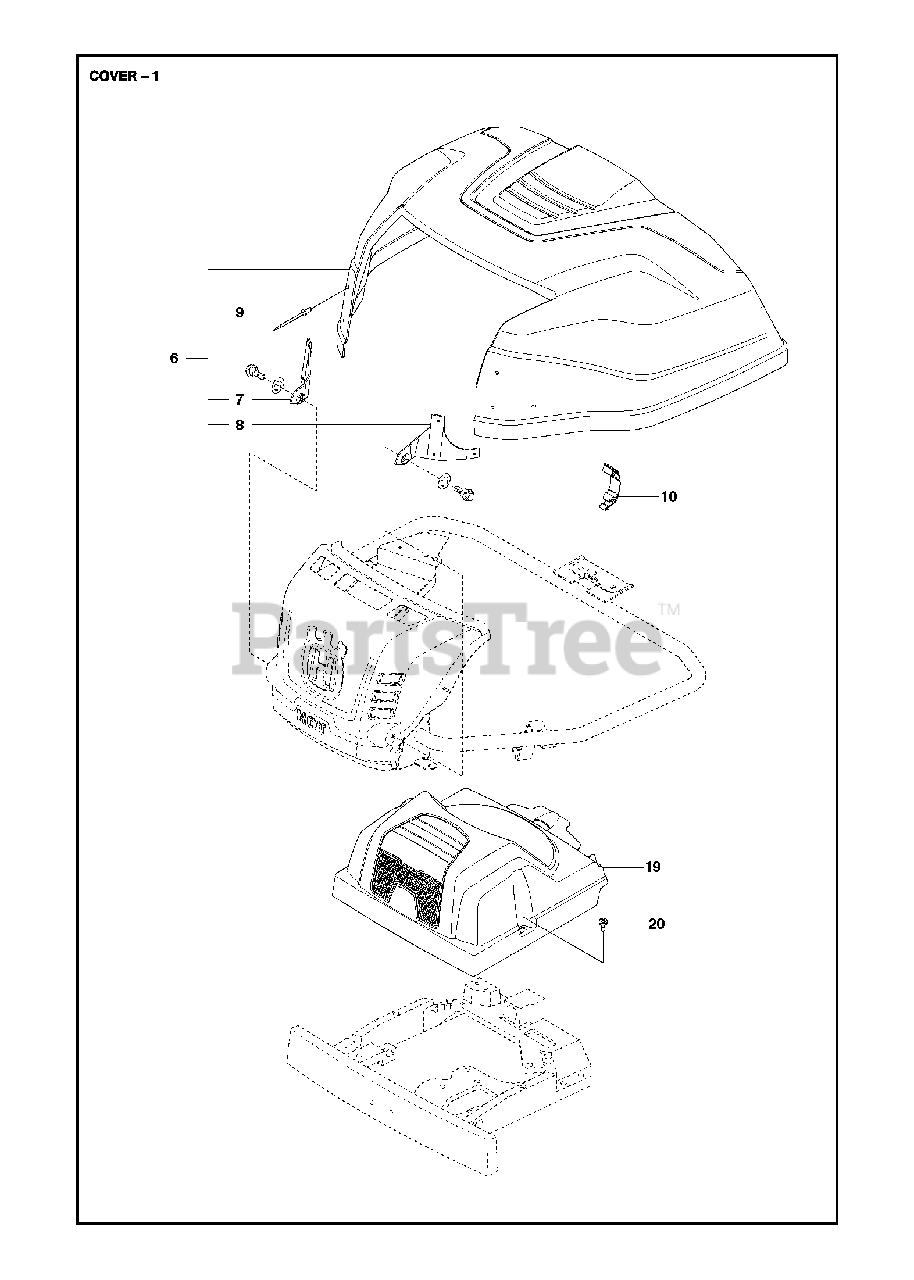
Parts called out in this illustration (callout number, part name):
9	RIVET
10	CLIP GRAY
19	TRANSMISSION COVER
